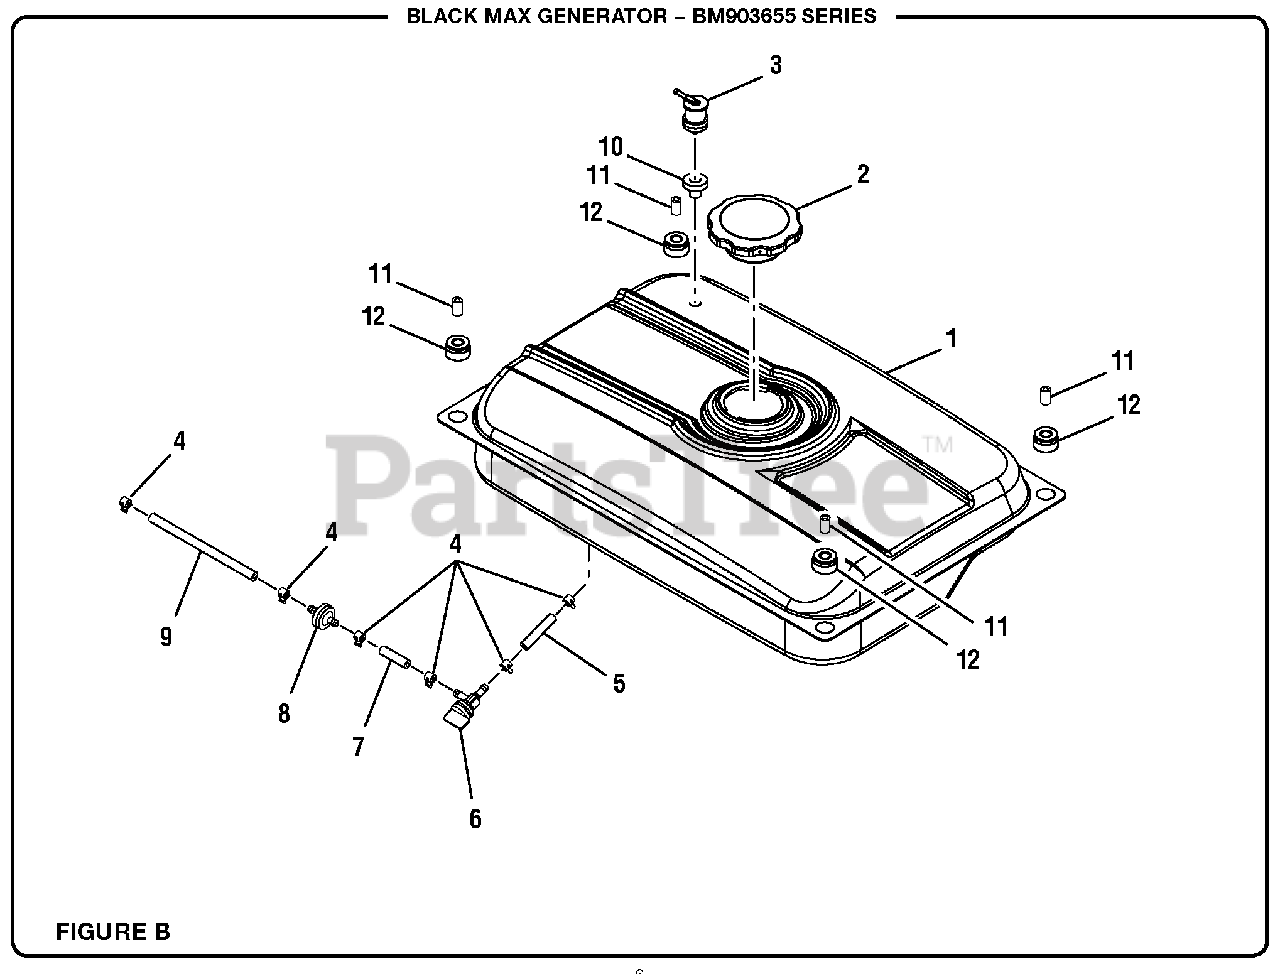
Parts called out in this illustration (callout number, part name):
1	Fuel Tank
3	Rollover Valve
5	Fuel Hose (45 mm)
6	Fuel Shut Off Valve
7	Fuel Hose (35 mm)
8	Fuel Filter
9	Fuel Line (144 mm)
